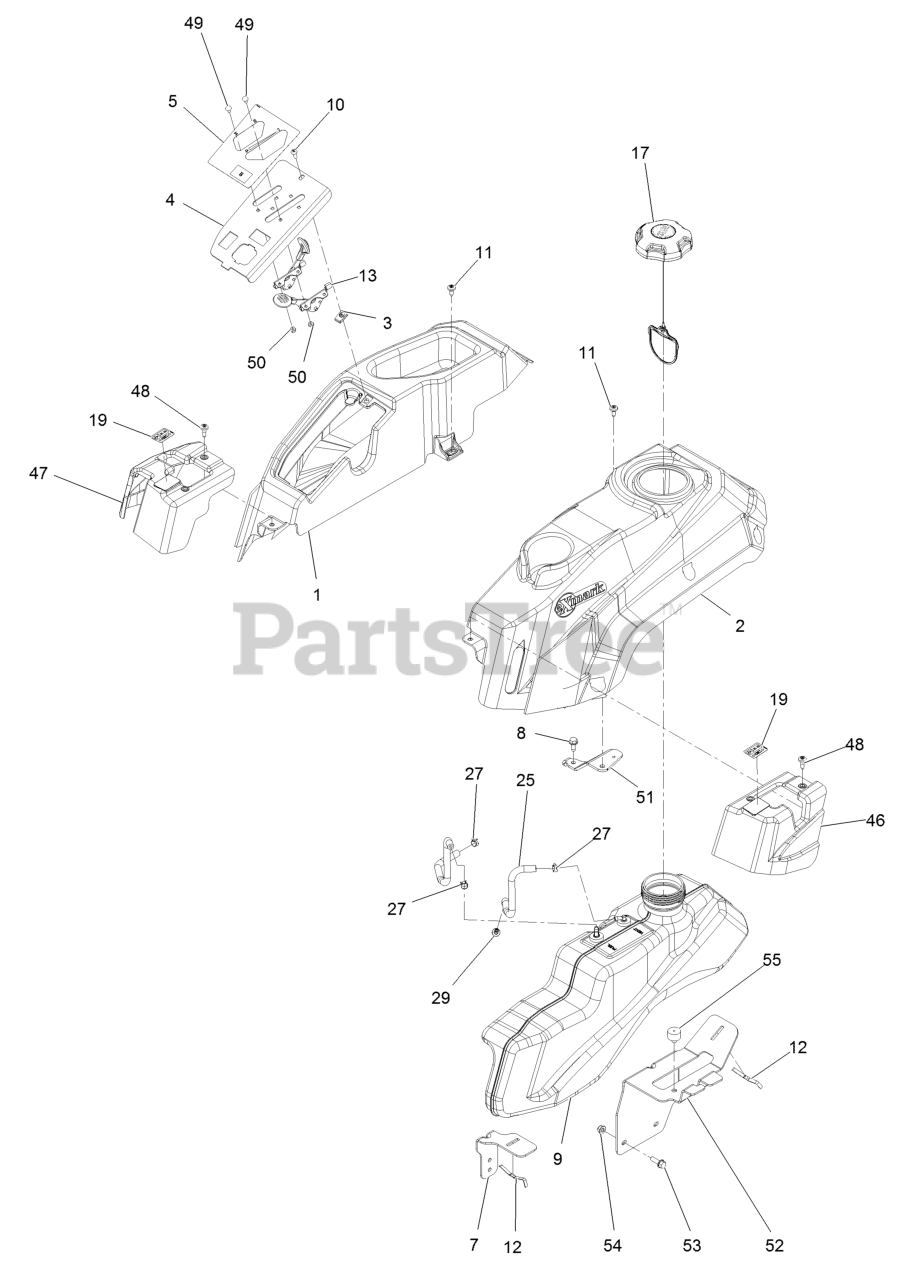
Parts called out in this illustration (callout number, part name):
1	Pod-RH, Narrow
2	Pod-LH, Narrow
3	Nut-Retainer-Panel 1/4-20
4	Panel-Control, Narrow
5	Decal-Control
7	Support-Tank [black]
8	Screw-HWH 5/16-18 X 3/4 Tf
9	Tank, Fuel
10	Screw-PPH 1/4-20 X 3/4
11	Screw-1/4-20 X 1/2 Tf Torx Plus
12	Spring
13	Cable-Control, Throttle
13	Cable-Control, Choke
17	Cap-Fuel, Ratcheting
19	Decal-Motion Control
25	Hose-Fuel Line 10 1/2"
25	Hose-Fuel
27	Clamp-Hose
28	Tie-Cable
29	Adaptor-Orifice
46	Cover, Motion Control LH
47	Cover, Motion Control RH
48	Screw-Shoulder
49	Bolt-Carriage #10-24 X 1/2
50	Nut-Nyloc #10-24
51	Bracket-Clamp
52	Bracket-Support Tank
53	Screw-HH Flg 5/16-18 X 1
54	Nut-Nyloc 5/16-18 Flg
55	Bumper-Grommet
